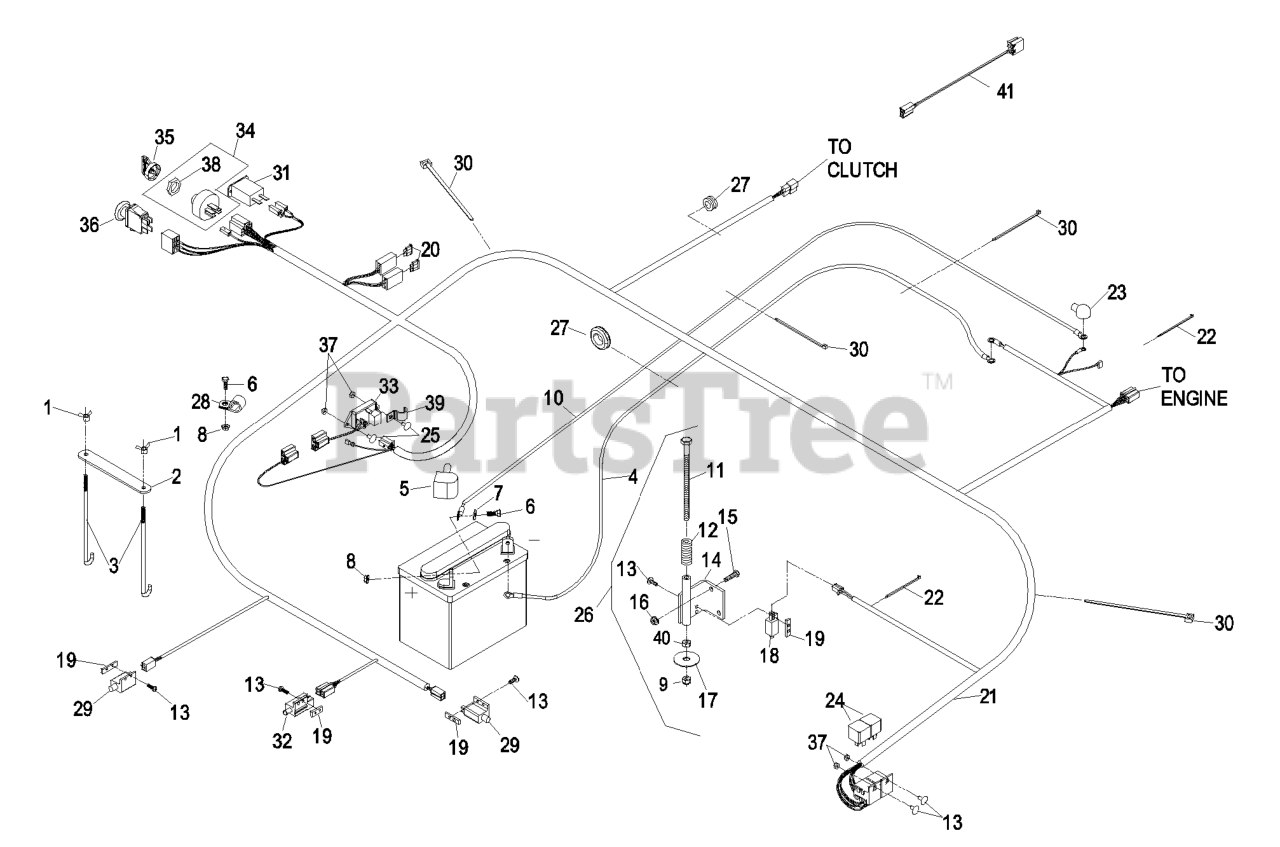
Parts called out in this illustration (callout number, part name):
1	WINGNUT
2	STRAP-HOLDDOWN, BATTERY
3	BOLT-HOLDDOWN
4	CABLE-GROUND, NEGATIVE
5	INSULATOR-BATTERY
6	SCREW-HH
7	WASHER-FLAT
9	NUT-LOCK, NI
10	POSITIVE BATTERY CABLE AS
11	SCREW-HH
12	SPRING-SWITCH, SEAT
13	SCREW-PPH
14	BRACKET-SWITCH, SEAT
15	SCREW-HH
18	SWITCH-CLOSED, NORMALLY
19	PLATE-TAPPED
20	FUSE-BLADE TYPE, 20 AMP
21	HARNESS,WIRE LHP KC
22	TIE-CABLE
23	INSULATOR-SOLENOID
25	SCREW-HEAD, TRUSS
26	ASM,SEAT SWITCH ACTUATOR
27	GROMMET
28	CLIP-LOOM
29	SWITCH-OPEN, NORMALLY
30	TIE-PLASTIC
31	METER-HOUR
33	MODULE-DELAY, SEAT
34	ASM,SWITCH W/NUT
35	KEY-IGNITION
36	SWITCH-PTO
37	NUT-LOCK, NI
38	NUT-SWITCH, IGNITION
39	CLIP-HALF, LOOM
40	NUT-HEX
41	HARNESS-CLUTCH
